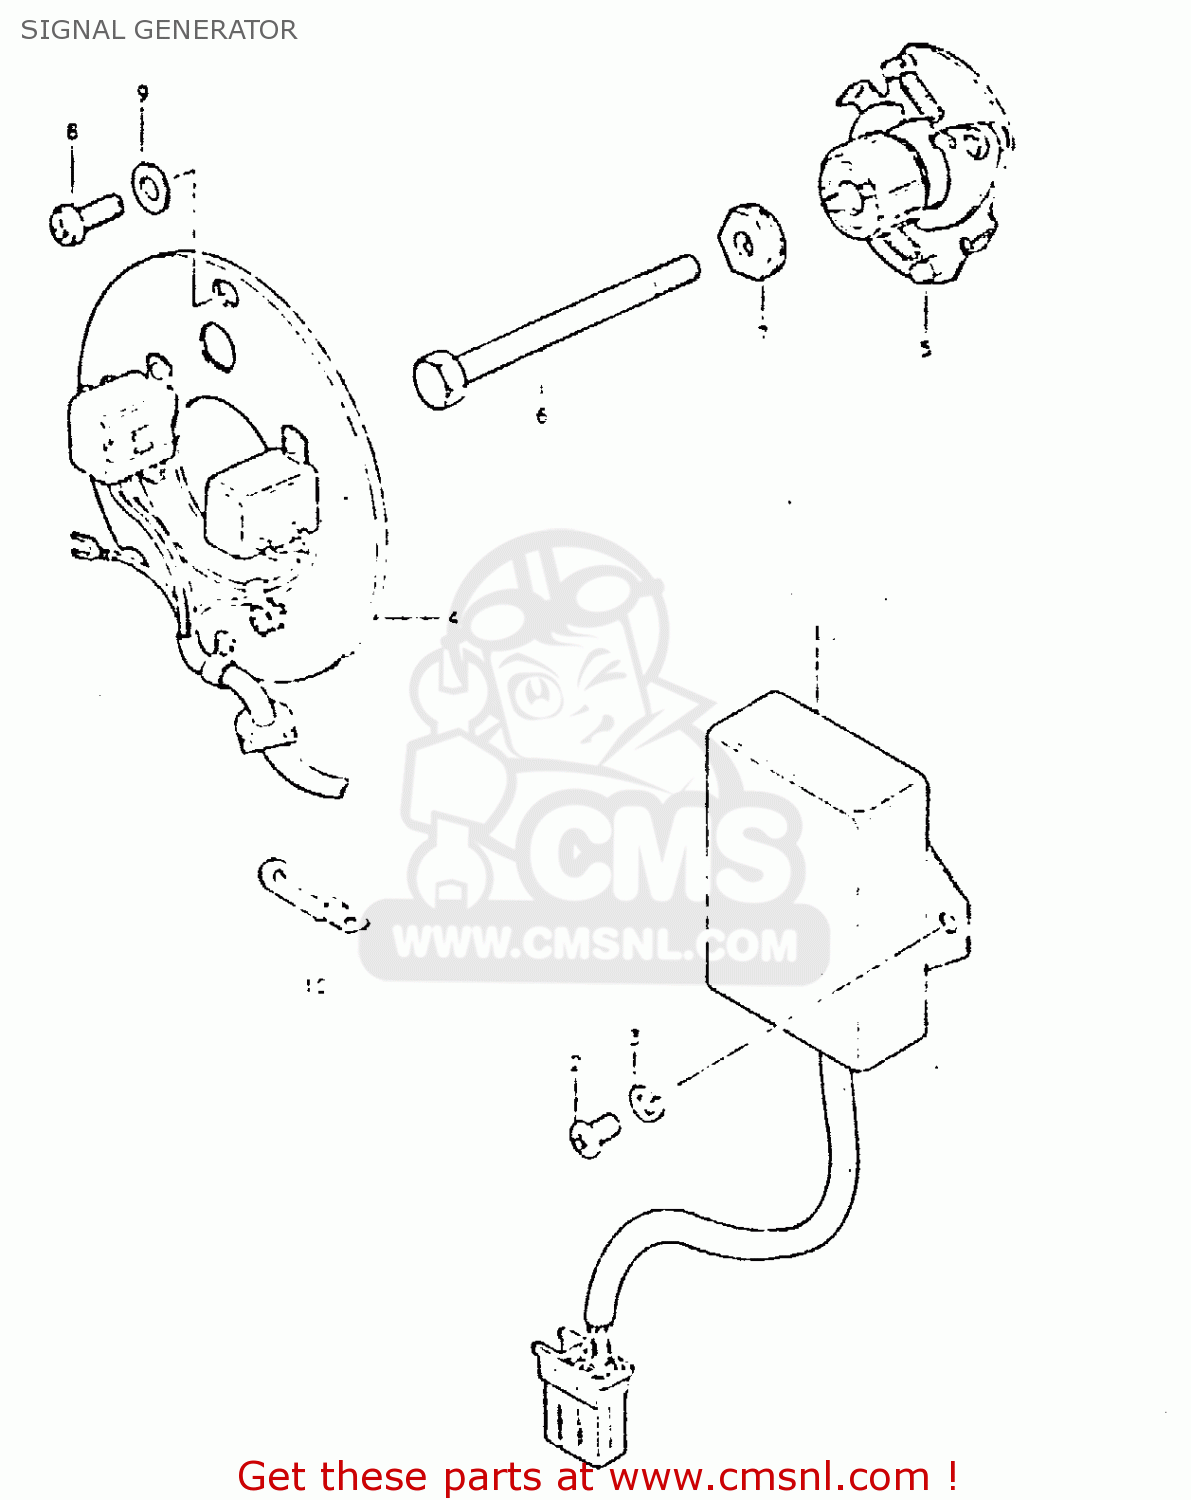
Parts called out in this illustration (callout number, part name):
1	CDI UNIT KOKUSAN
2	SCREW
3	LOCK WASHER
4	SIGNAL GENERATOR ASSEMBLY
5	GOVERNOR ASSEMBLY
6	BOLT 6X60
7	WASHER,CONTACT BREAKER
8	SCREW(5X12)
9	WASHER
10	CLAMP L:35
